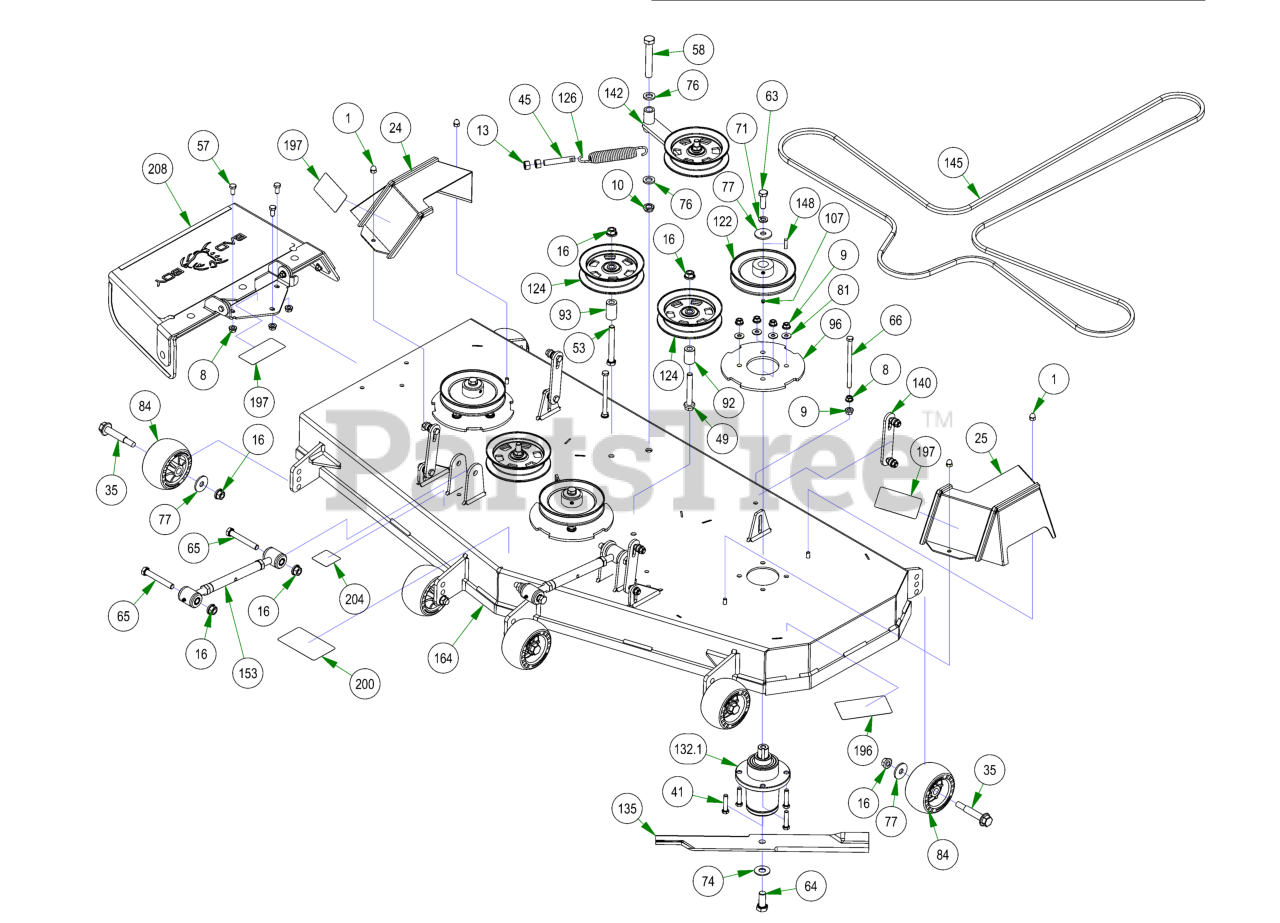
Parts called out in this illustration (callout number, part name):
1	5/16-18 ACORN NUT HIGH-CROWN ZC
8	3/8-16 HEX SERRATED FLANGE NUT HARD/ZINC
9	3/8-16 NYLON INSERT FLANGE LOCKNUT (GR.F) ZINC
10	5/8-11 NYLON INSERT JAM LOCKNUT ZINC
13	1/2-13 HEX NUT ZINC
16	1/2-13 NYLON INSERT FLANGE LOCKNUT ZINC
24	2021 Maverick 54”/60” RH Pulley Cover
25	2021 Maverick 54”/60” LH Pulley Cover
35	Deck Wheel Bolt
41	3/8-16 X 1-3/4 HEX C/S (GR.5) ZC
45	All Thread
49	1/2-13 X 3-1/2 HEX FLANGE BOLT (GR.8) ZINC
53	1/2-13 X 4 HEX CAP SCREW (GR.8) ZINC YELLOW
57	3/8-16 X 3/4 HEX CAP SCREW (GR.5) ZINC
58	5/8-11 X 4 HEX CAP SCREW (GR.8) ZINC YELLOW
63	1/2-20 X 1-1/2 HEX CAP SCREW (GR.5) ZINC
64	5/8-18 X 1-1/2 HEX CAP SCREW (GR.8) ZINC YELLOW
65	1/2-13 X 3-1/2 HEX CAP SCREW (GR.5) ZINC
66	3/8-16 X 5-1/2 HEX CAP SCREW (GR.5) ZINC
71	1/2 SPLIT LOCKWASHER (GR.8) ZINC/YELLOW
74	5/8 USS FLAT WASHER (1-3/4" OD) GR.8 ZINC YELLOW
76	.635 ID X 1.120 OD X .140 THICK FLAT WASHER NYLON
77	1/2 BELLEVILLE WASHER (1-5/8 OD X .140 THK) ZINC
81	5/16 USS FLAT WASHER (7/8 OD) ZINC
84	Deck Wheel
92	.502 ID X .750 OD X 1.500 Long Spacer
93	1 3/4" Pulley Spacer
96	Deck Spindle Support Plate
107	5/16-24 X 1/4 SOCKET SET SCREW (CUP PT) PLAIN
122	6 1/4" Drive Pulley
124	5-3/4 Idler Pulley
126	Deck Idler Spring
132	Spindle Assembly
135	60" High Lift Fusion Blade
140	Deck Hanger Assembly
142	2017 MZ/ZT Deck Idler Assembly
148	1/4 X 1 SQ MACHINERY KEY 1018 STL PLN
153	2018 Maverick Turnbuckle (Top Link)
164	2023 60" x 5" Deck
196	2018 60" Deck Decal
197	Danger Decal-Spindle/Discharge
200	Deck Belt Route Decal
204	Deck Impact Patent Decal 9591803
208	Discharge Chute Assembly
